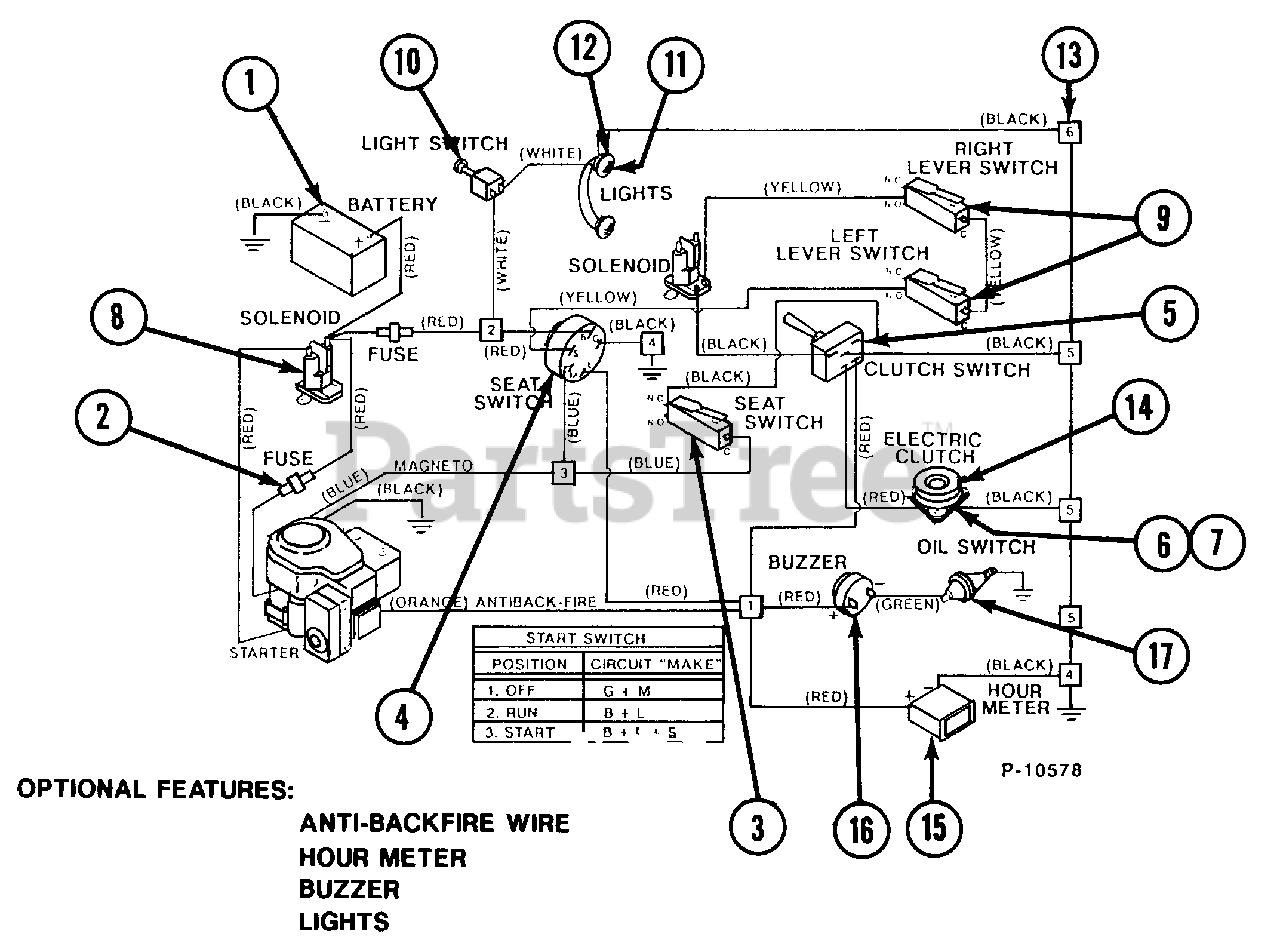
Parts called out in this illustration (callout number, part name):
1	BATTERY
2	FUSE HOLDER (INLINE)
3	SEAT SWITCH
4	START SWITCH
5	CLUTCH SWITCH
6	TERMINAL
7	INSULATOR COVER
8	SOLENOID
9	NEUTRAL SWITCH
10	HEADLIGHT SWITCH
11	HEADLIGHT
12	HEADLIGHT MOUNTING RING
13	6 POINT TERMINAL BOARD
14	ELECTRIC CLUTCH
15	HOUR METER
16	BUZZER
17	OIL PRESSURE SWITCH
